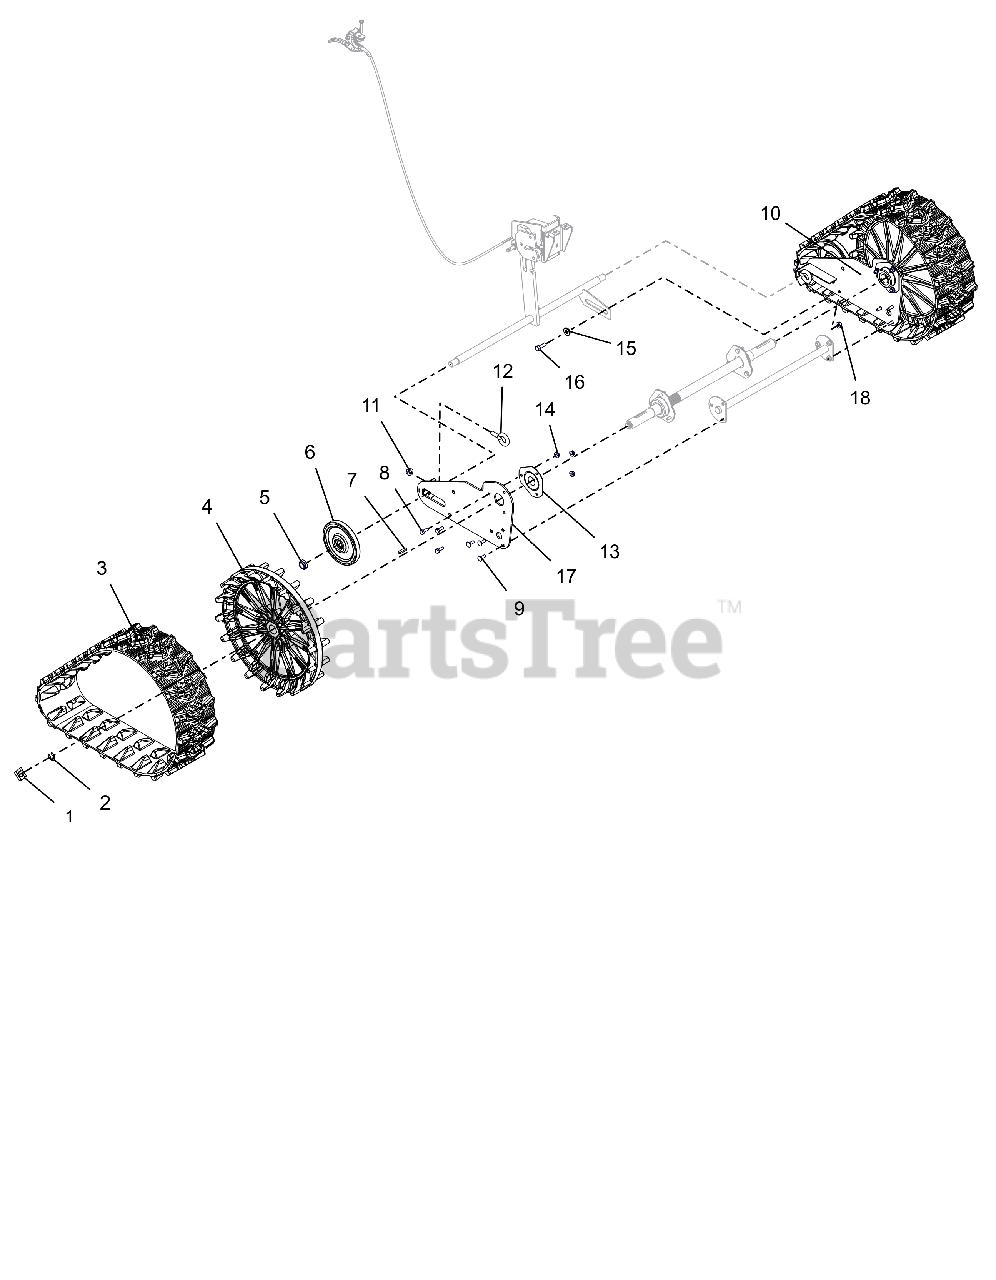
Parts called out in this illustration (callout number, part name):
1	CLIP, SNAP .625 DIA
2	RG-RTNG-EXT .625X.042
3	TRACK, RUBBER - 22 PITCHES
4	SPROCKET, LARGE TRACK DRIVE
5	NUT, NYL LK .625-18 ZCC
6	WHEEL, BOGIE - SINGLE BEARING
7	KEY-RECT .25X.188X1.00
8	BLT, HEX .25-20X.75 G5 ZCC
9	BLT, RHSN .25-20X.750 G5 ZCC
10	PLATE, SIDE-BWT LH WLDMT
11	NUT-LK-CTR-FLG .375-16 GF ZCC
12	BLT-EYE .375-16X.880 YWZC
13	BRG-FLG 1.003/1.000 3 BOLT
14	NUT-LK-TOP-FLG .250-20 GF ZCC
15	BSHG-FLG .325X.499X.3X.875
16	BLT,HEX .31-18X1.00 G5 ZCC
17	PLATE, SIDE-BWT RH WLDMT
18	NUT-LK-TOP-FLG .312-18 GF ZCC
